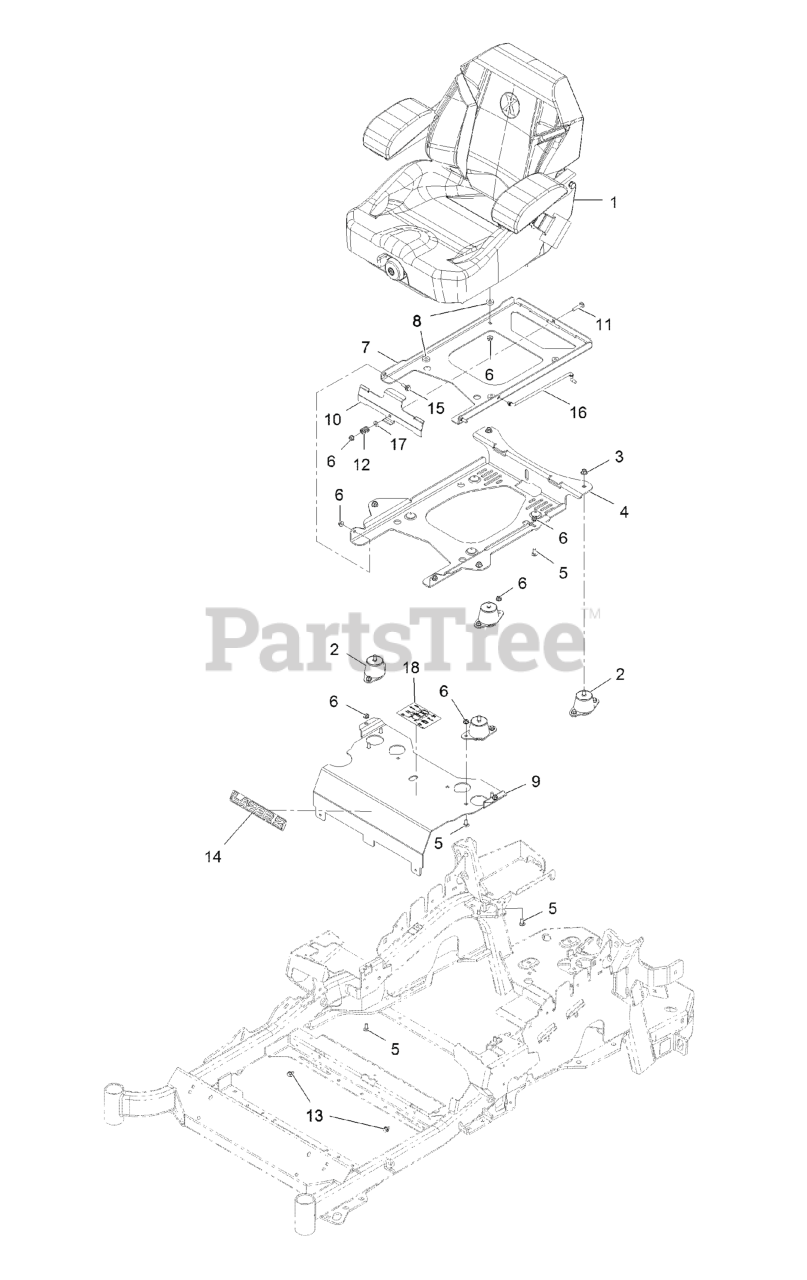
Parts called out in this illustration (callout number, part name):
1	KIT-SUSPENSION SEAT
2	ISOLATOR-SEAT
3	NUT-HF, NI
4	PLATE-TILT, SEAT SUPPORT
5	SCREW-CARR
6	NUT-HF, NI
7	PLATE-FRAME, SEAT
9	Panel-Front, Seat Mount
10	PLATE-LATCH, SEAT
11	BOLT-CARR
12	SPRING-COMPRESSION
14	DECAL, LAZER MODEL
15	SCREW-SHOULDER
16	ROD-PROP
17	WASHER-PLAIN
18	DECAL-SERVICE AID
